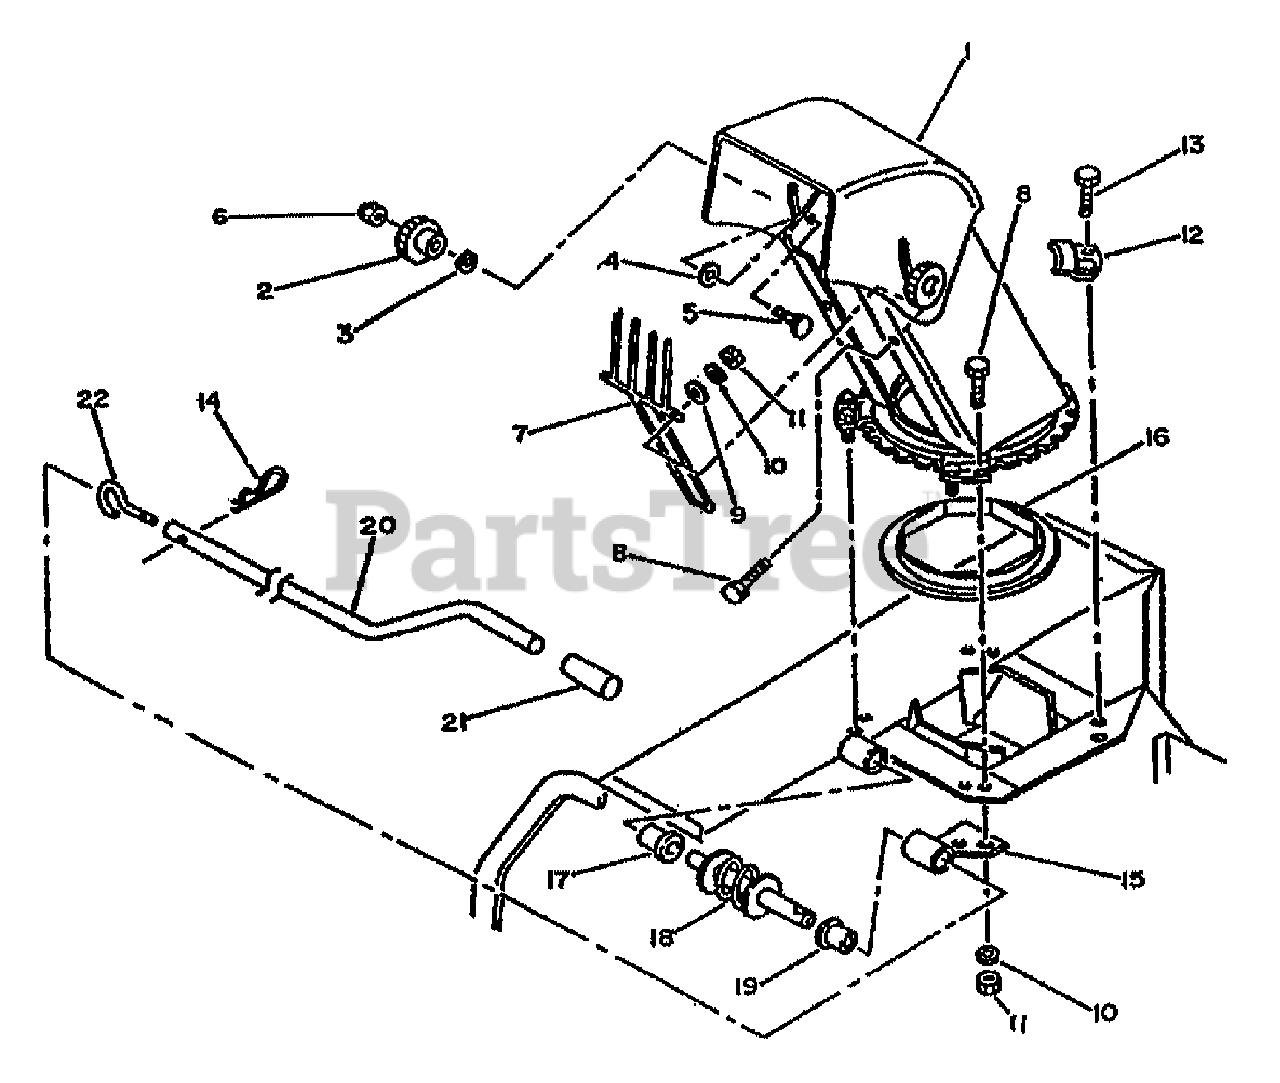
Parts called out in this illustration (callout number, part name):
1	ASSM-CHUTE & DEFLECTOR
3	WASHER-NYLON .3438 (11/32 HOLE
4	WASHER-.438 NYLON (7/16 HOLE)
5	BOLT-CARR .312
6	NUT-TOP/LK 5/16-18 ZP
7	GUARD-HAND
8	SCR-HH 1/4-20X.75 G5 ZP
9	WASHER-FLAT 5/16 SAE
10	WASHER-LK .25 ZP
11	NUT-H/LK 1/4-20
12	PLATE-RETAINING
13	SCR-HH 1/4-20X.5 GR5 YEL
13	SCR-HH 1/4-20X.75 G5 ZP
14	WASHER-LK .375 @ DEPL
15	SUPT-WORM
16	RING-NYLON
17	BUSHING
18	WORM-ROTATION
19	BUSHING
20	HANDLE
21	GRIP-HANDLE
22	HOOK-HANDLE
